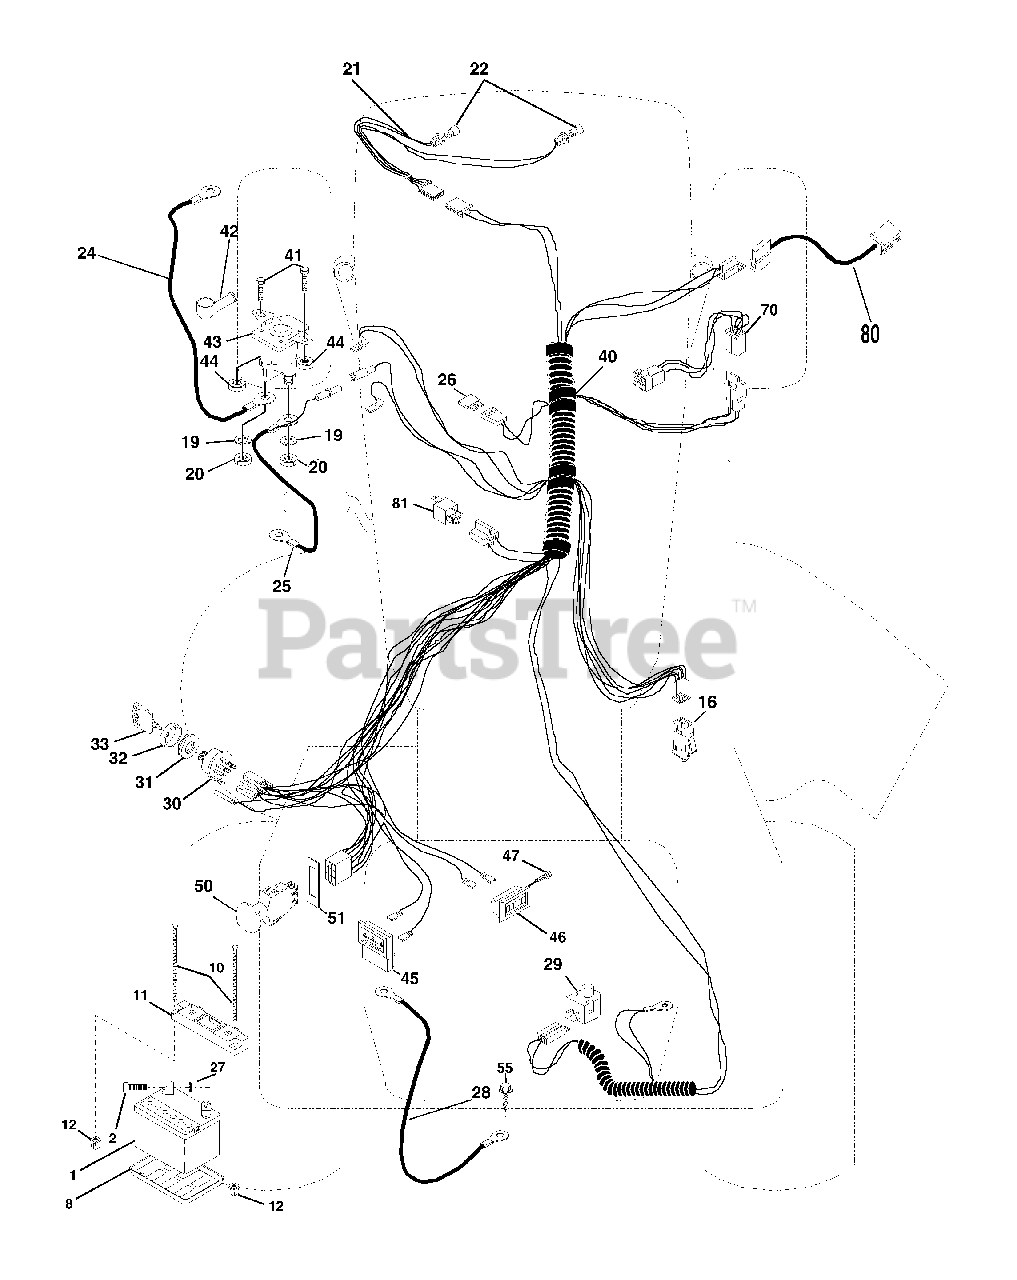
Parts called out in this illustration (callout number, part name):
1	Battery 12 Volt 25 AMP
2	Bolt Hex Hd 1/4-20unc X 3/4
8	Tray Battery 7.80 x 5.25 Blk
10	Bolt Btr Frt 1/2-20 x 7.5 Zinc
11	Holddown Battery Front Mount
12	Nut Push Nylon 1/4" Battery Frt
16	Switch Interlock Push-In
19	Washer Lock 1/4
20	Nut Jam Hex 1/4-20 Unc
21	Harness Asm Light W/4152j
22	Bulb Light #1156
24	Cable Battery 6 Ga 11" red
25	Cable Battery 6 Ga 44" red w/16 wire
26	Fuse 15 AMP
27	Nut Keps Hex 1/4-20 Unc
28	Cable Ground 6 Ga 21" black
29	Switch Plunger Nc Gray
30	Switch Ign 4 pos w/lights
31	Nut Ignition
32	Cover Sw Ignition
33	Key Ign Modelled Generic
40	Harness Ign.
41	Bolt Blk Fin Hex 1/4 - 20 x 1/2
42	Cover Terminal Red
43	Solenoid
44	Nut Keps Hex 1/4-20 Unc
45	Ammeter Rectangular 15 Amp
46	Meter Hour
47	Screw 10-24 x 1/2 Black
50	Switch PTO 3PDT Black Delta 96
51	Ring Retainer PTO
55	Screw Thdrol 5/16-18 x 1/2 Tyt
70	Harness, Eng
80	Harness Clutch Evx
81	Relay Asm.
